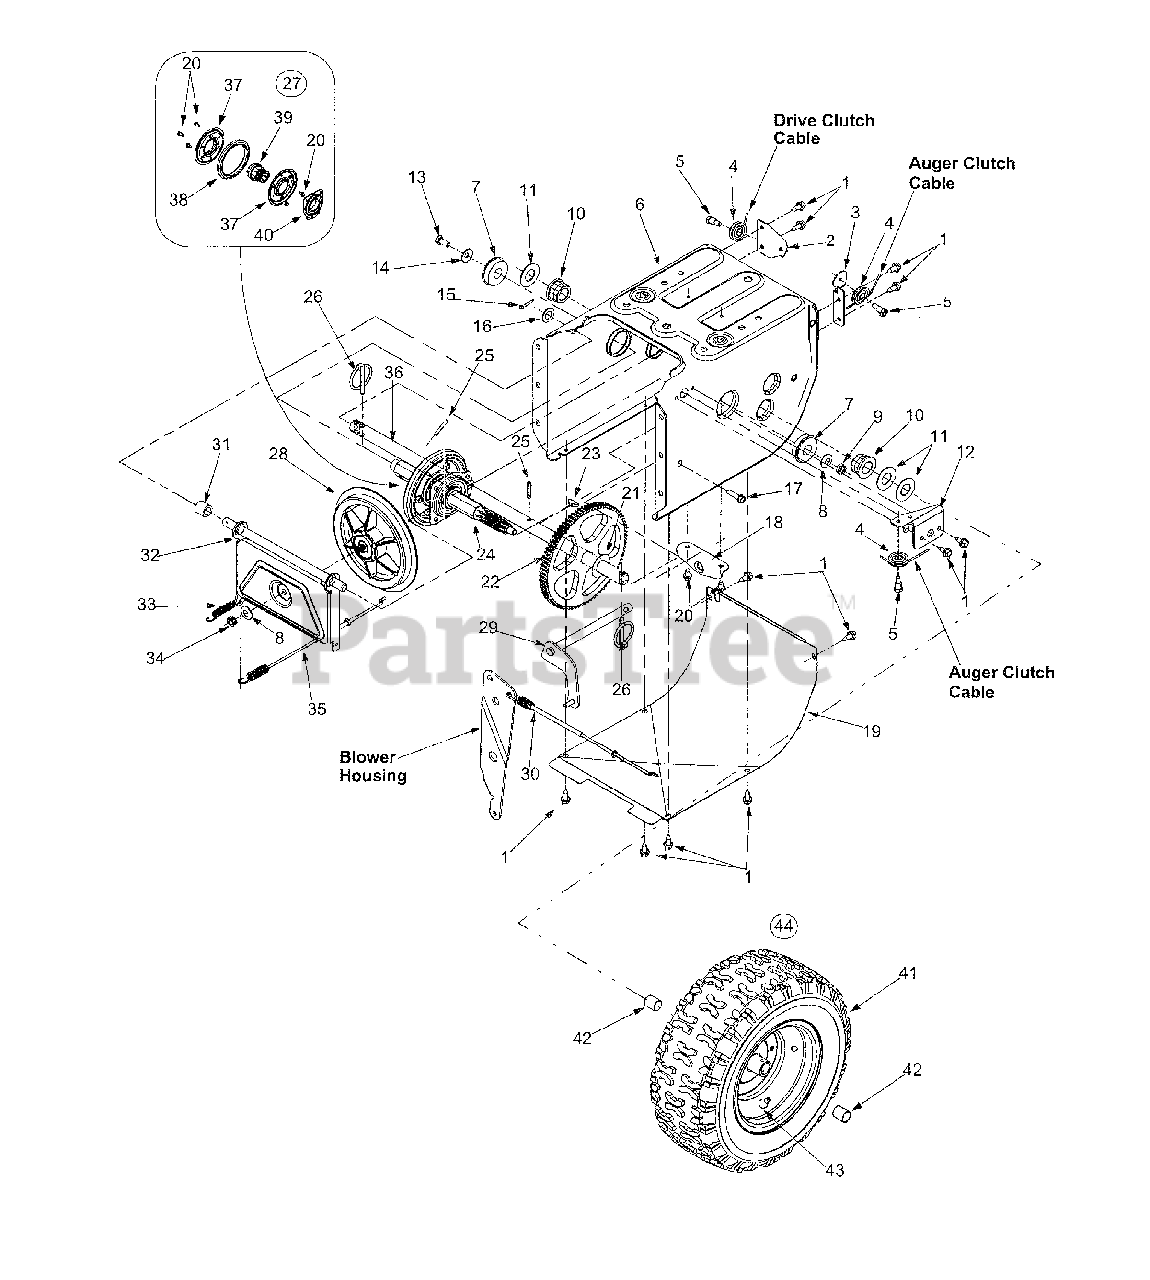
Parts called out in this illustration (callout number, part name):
5	Hex Screw 1/4-28
9	Lock Jam Nut
10	Hex Flange Bearing
14	Bell Washer .340 ID x .872 OD
16	Flat Washer .536 ID x .930 OD
17	Hex Washer Scr 1/4-20 x 1.25
21	Flat Washer .760 ID x .50 OD
24	7-Tooth Shaft
25	Roll Pin
26	Click Pin
27	Friction Wheel Assembly
28	Friction Disc Wheel
29	Wheel Shift Rod Assembly
30	Drive Cable
34	Jam Nut, 3/8-24
35	Drive Cable
37	Friction Plate
38	Friction Wheel
39	Friction Wheel Hub
40	Friction Wheel Bearing
42	Sleeve Bearing
43	Air Valve
